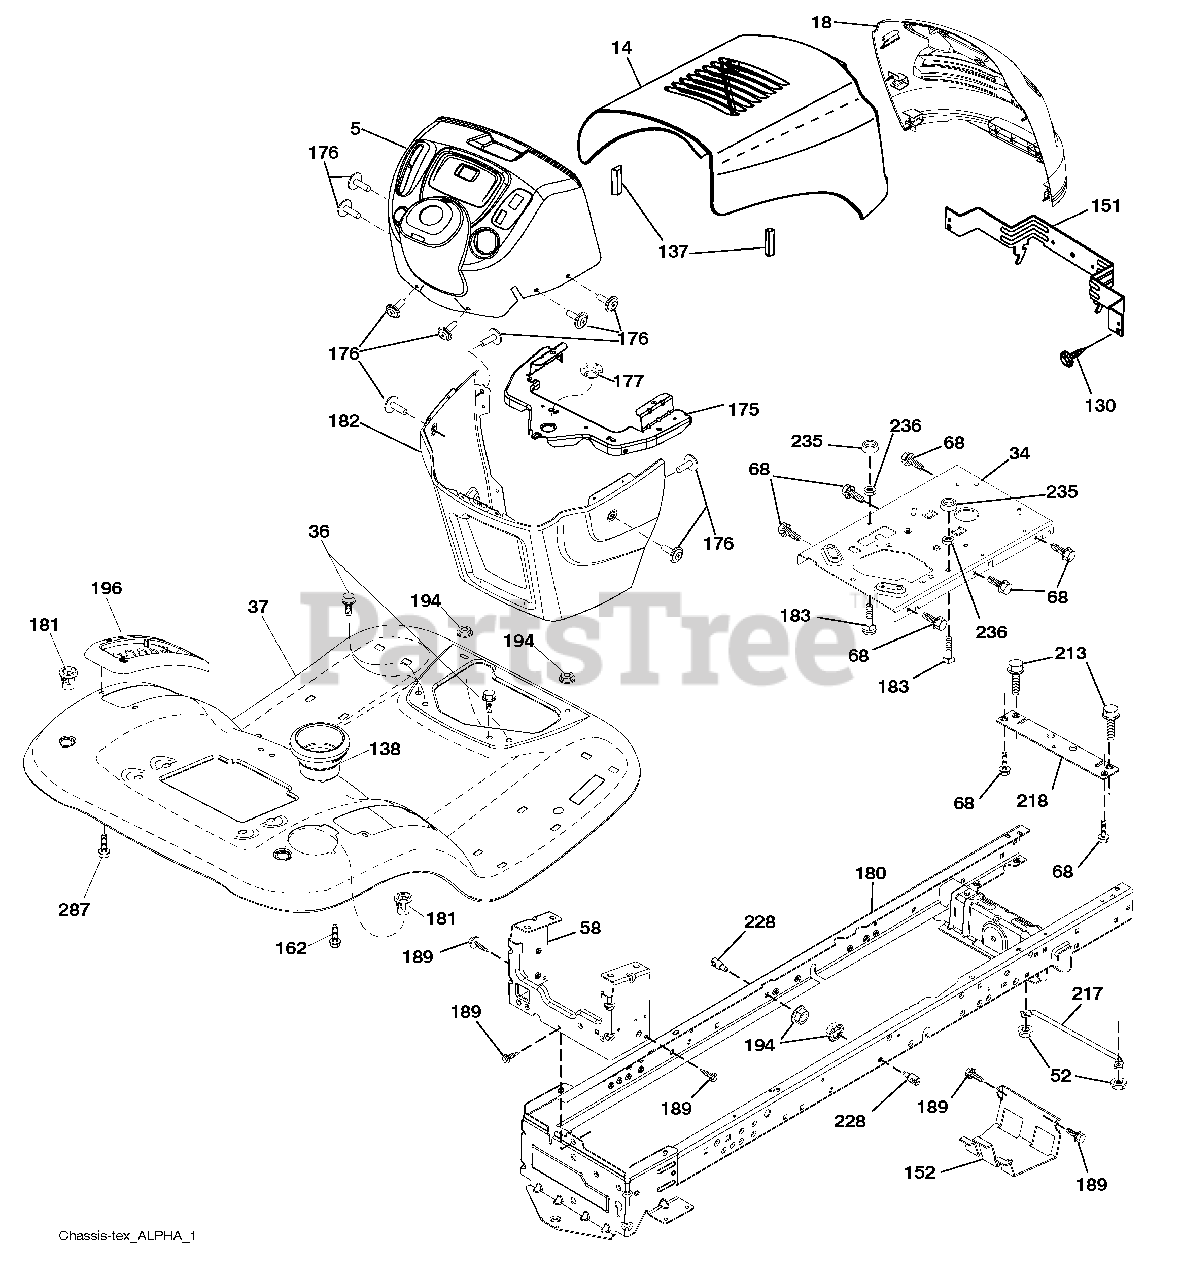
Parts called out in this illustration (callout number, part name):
5	Dash
14	Hood
18	Grille
34	Plate Engine
36	Screw 5/16-18 x 3/4
37	Fender
52	Nut Lock 5/16-18
58	Drawbar Upper
68	Screw Thdrol 5/16-18 x 1/2
130	Screw #10 x 0.750
137	Bumper Hood
138	Cupholder
151	Bracket Pivot
152	Shield Browning/Debris
162	Screw Hex Wsh Hi-Lo 1/4 x 1/2
175	Crossmember
176	Screw 10-24 x 5/8 Wshd Qdrx
177	Bushing Steering
181	Bushing Mtg. Fender Crgo.
182	Dash Lower
183	Bolt Fin Hex 5/16-18 x 1-1/4
189	Screw 5/16-18 x 3/4
194	Nut Lock Hex Flange 5/16-18
196	Console Asm. Deck Lift
213	Bolt 5/16-18 x 3/4
217	Rod Pivot Hood
218	X-Piece Hood Stop
228	Stud Fastener
235	Spacer Fender
236	Nut Center Lock 5/16-18
287	Screw 1/4-20 x 3/8
287	Plug Switch Light
